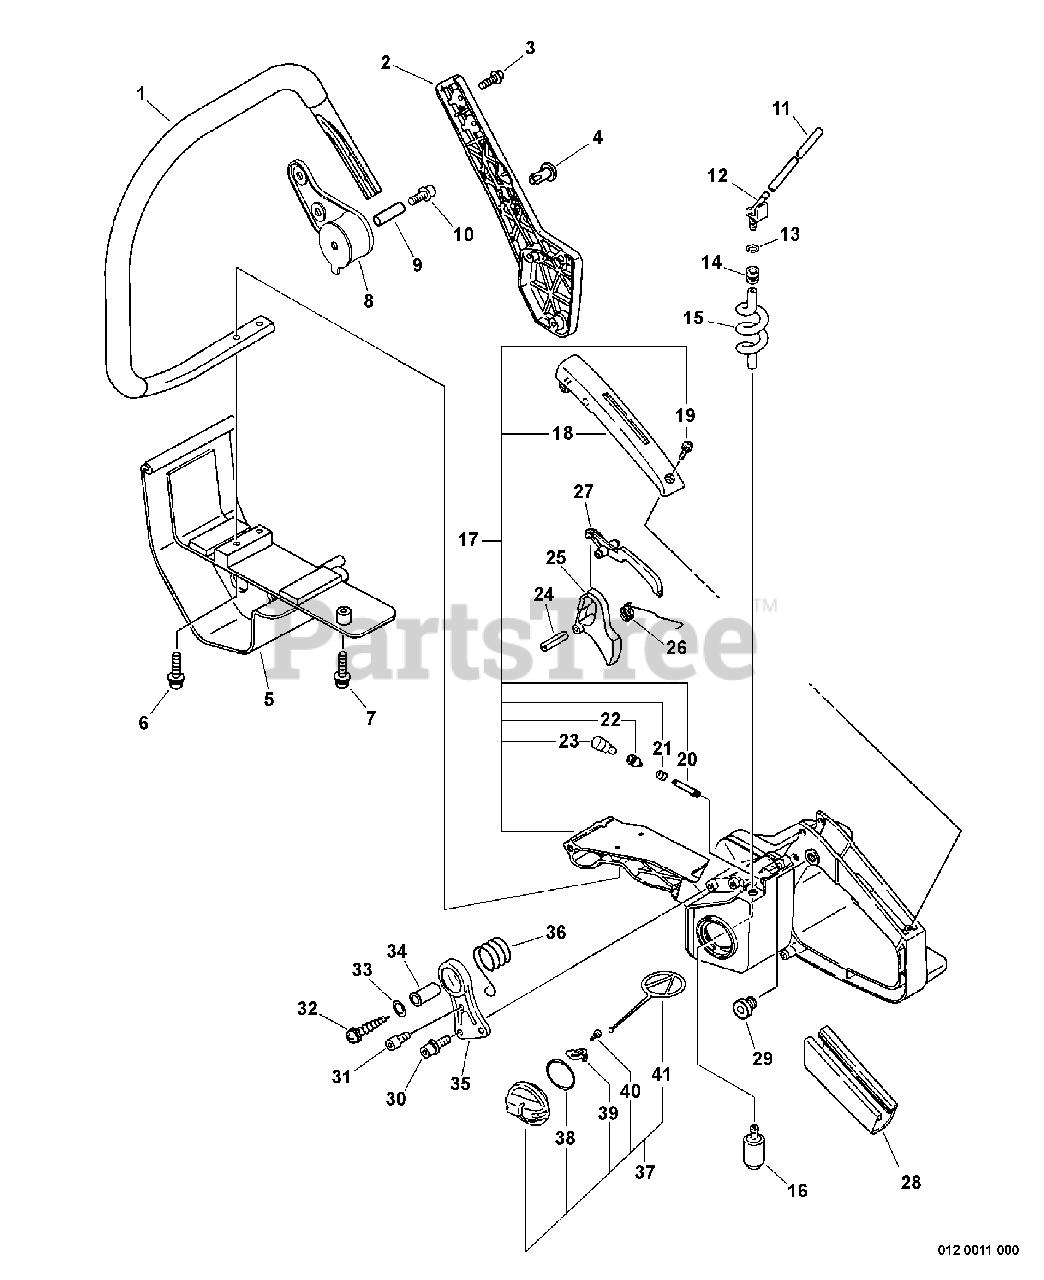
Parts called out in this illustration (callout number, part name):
1	HANDLE - FRONT
2	BRACKET, HANDLE
3	SCREW - 5X20
6	SCREW - 5X30
7	SCREW - 5X25
8	CUSHION
9	COLLAR - 5
10	SCREW - 5X20
11	PIPE - 3X6X110 -- BLACK
12	CONNECTOR, PIPE
13	CLIP - 6.5
14	GROMMET
15	PIPE - BLACK
16	FILTER, FUEL
17	HANDLE ASSY - REAR
18	COVER, HANDLE
19	SCREW - 4X14
20	PIPE - VENT
21	CLIP - 5.5
22	COVER, VENT
23	VENT, FUEL TANK
24	PIN - SPRING -- 5X25
25	TRIGGER, THROTTLE
26	SPRING, TRIGGER
27	LEVER, TRIGGER LOCKOUT
28	GRIP, HANDLE
30	SCREW - 5X14
31	SCREW - 5X8
32	SCREW - 5X35
33	WASHER - 5
34	COLLAR - 5
35	BRACKET, CUSHION
37	CAP ASSY
38	O-RING - 29
39	RETAINER
40	SCREW - 3X8
41	CONNECTOR, CAP
